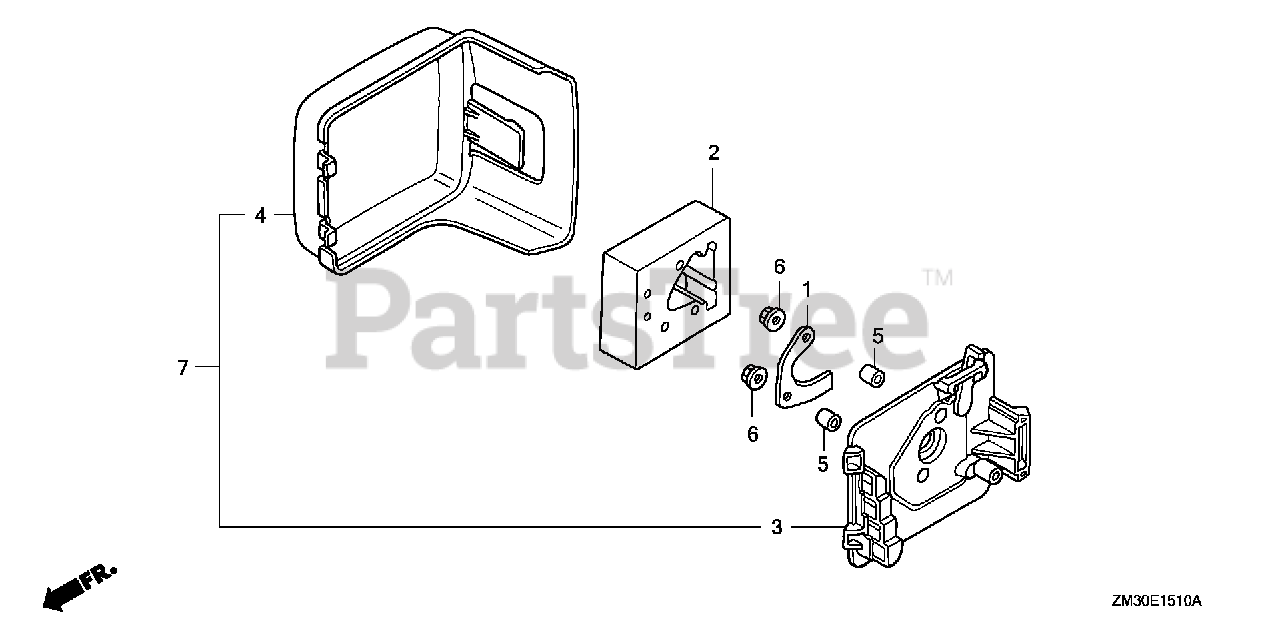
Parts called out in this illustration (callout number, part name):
1	PLATE, OIL TRAP
2	ELEMENT, AIR CLEANER (SEMI-DRY)
3	HOUSING, AIR CLEANER *R291R* (DARK POWER RED)
4	COVER, AIR CLEANER *R280* (POWER RED)
4	COVER, AIR CLEANER *R291R* (DARK POWER RED)
5	COLLAR, AIR CLEANER
6	NUT, FLANGE (5MM)
